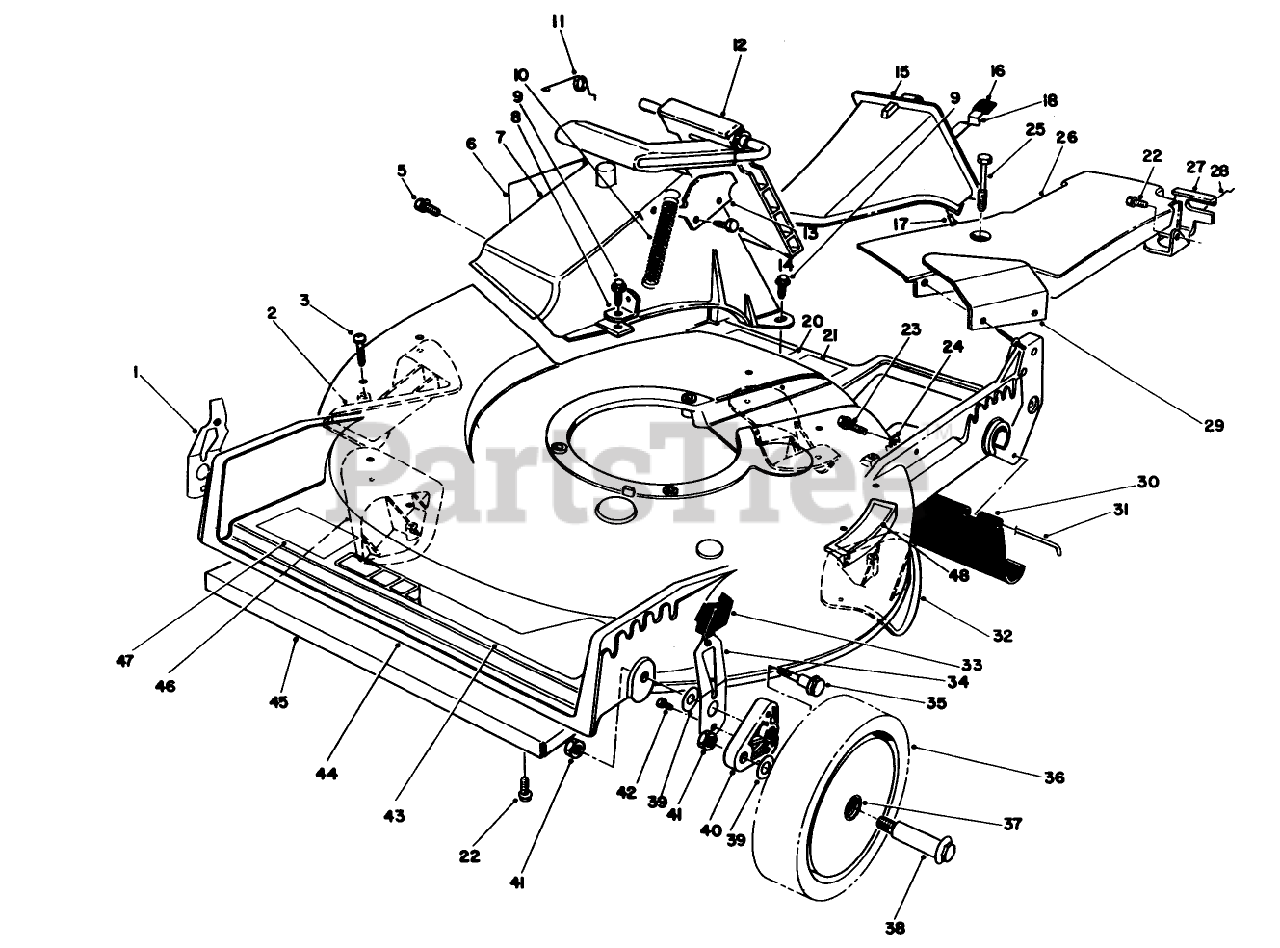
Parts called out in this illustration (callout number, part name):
1	RH SPRING ARM ASSEMBLY
2	KICKER
3	SCREW-PPH
5	SCREW AND WASHER ASM
7	TUNNEL-DISCHARGE
9	SCREW-HWH
10	SPRING-DOOR
11	RETAINER-DOOR
13	DOOR LATCH PLATE
14	SCREW-PLASTITE
15	DISCHARGE PLUG ASM
16	GRIP-LATCH
17	RIVET-HEAD, FLAT
18	LATCH-PLUG, DISCHARGE
19	KICKER
22	SCREW-HWHTF
23	SCREW-HWH
24	Clamp-R
25	SCREW-HWH
28	RETAINER-CABLE
31	ROD-SHIELD
32	KICKER
33	KNOB-ARM
34	LH SPRING ARM ASSEMBLY
35	SCREW-SHOULDER
37	BUSHING
38	WHEEL BOLT
39	WASHER
40	ARM-PIVOT, FRONT
42	SCREW-HWH
43	DECAL - DECK
46	KICKER
47	DECAL
48	DECAL - STEP PAD INT'L
